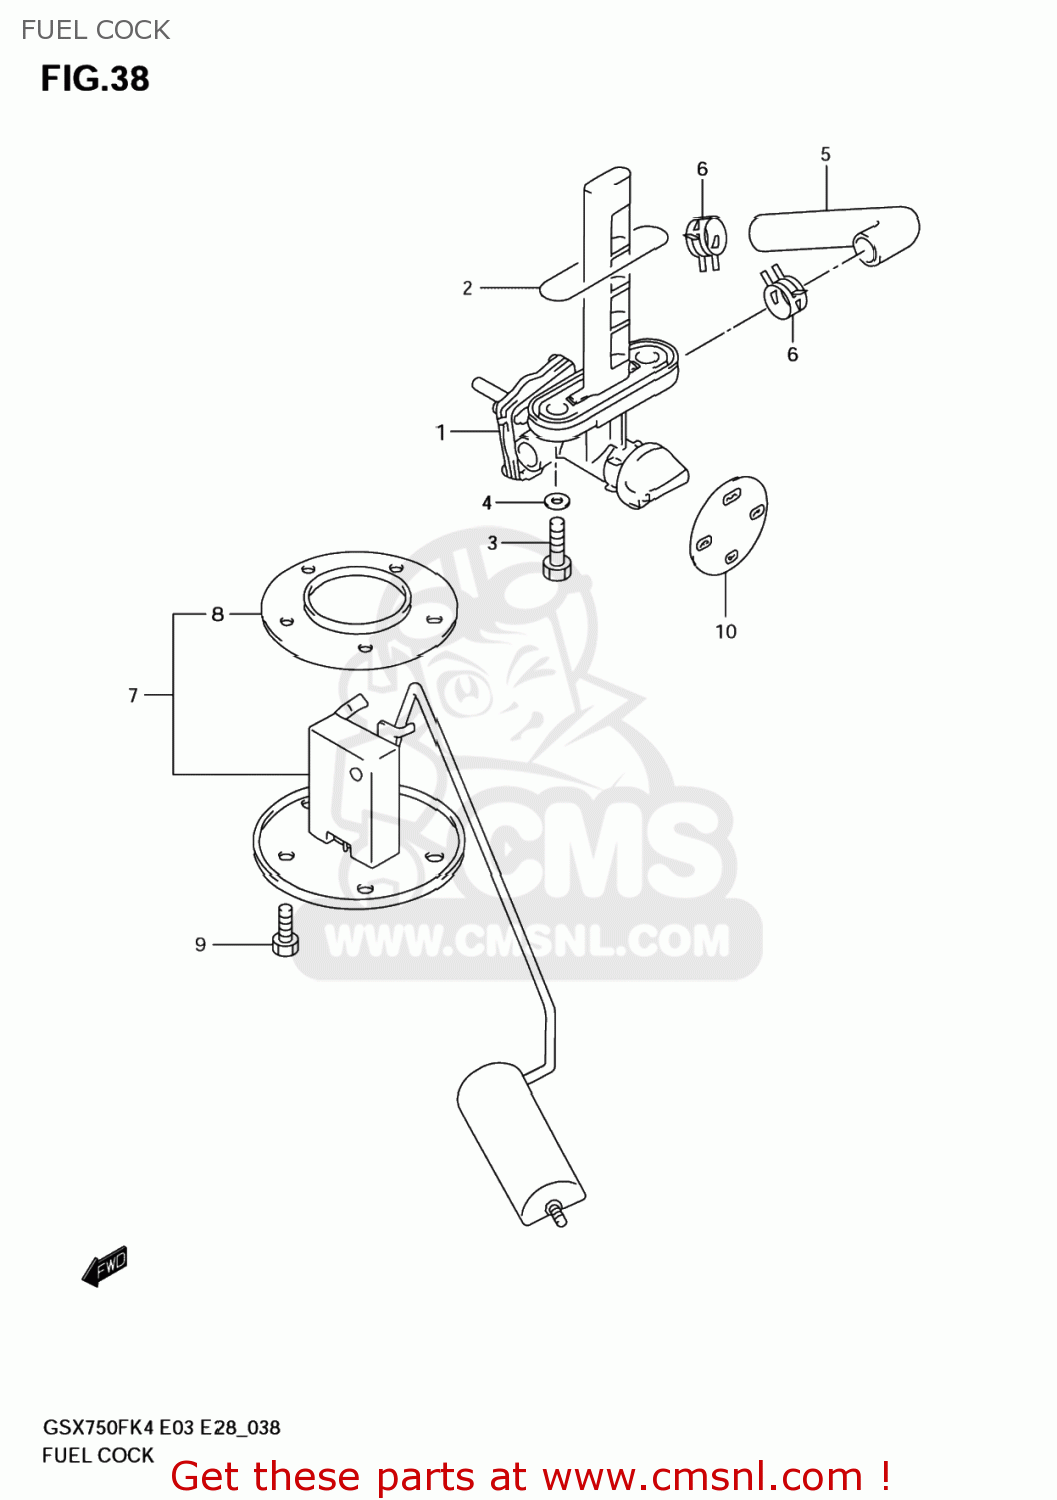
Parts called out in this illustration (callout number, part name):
1	COCK ASSEMBLY,FUEL
2	O RING
3	BOLT(6X20)
4	GASKET(6.4X11.5X0.8) (NAS)
5	HOSE,FUEL ON
6	CLIP
7	GAUGE ASSY,FUEL LEVEL SENDER
8	GASKET,FUEL LEVEL GAUGE (NAS)
9	BOLT 5X10
10	LABEL,FUEL COCK(SILVER)
